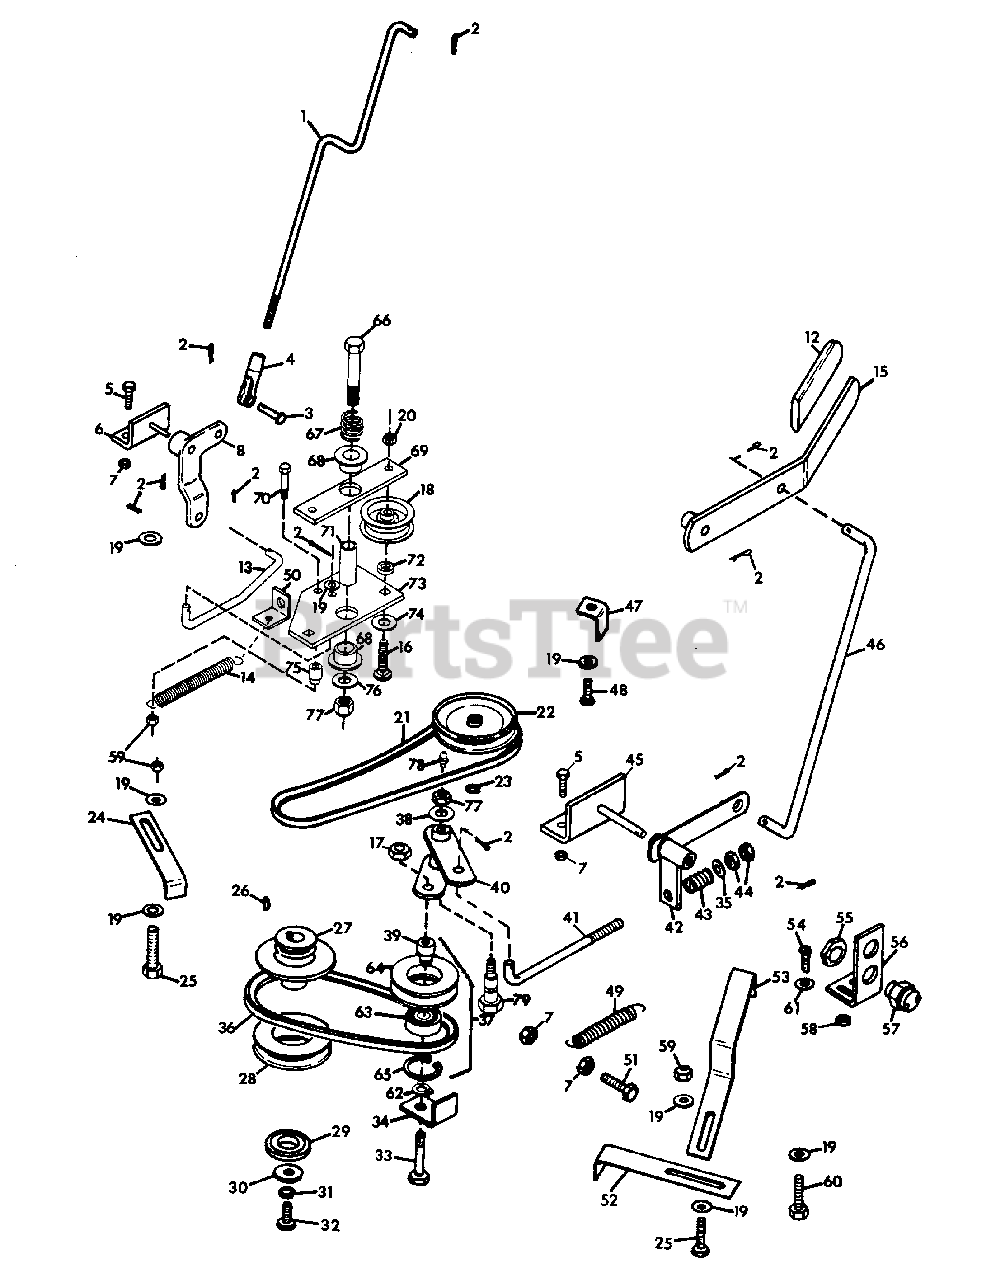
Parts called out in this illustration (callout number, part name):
1	NUT, LOCK 1/4-20
2	PIN, COTTER .09X.75
3	WASHER, SPRING
4	BOLT, HEX 1/4-20X1.75
5	PIN, COTTER .06X.50
6	LEVER, CLUTCH-BRAKE LOCK R.H.
7	PIVOT, BRAKE ROD
8	PIN, CLEVIS .312X.812
9	LEVER, HAND CLUTCH
10	PIN, CLEVIS .187X1.70
11	YOKE
12	ROD, WHEEL CLUTCH
13	ROD, BRAKE
14	GRIP, HANDLE
15	TIP, VINYL
16	WASHER, FRICTION
17	WASHER, FLAT .360X.875X.083
